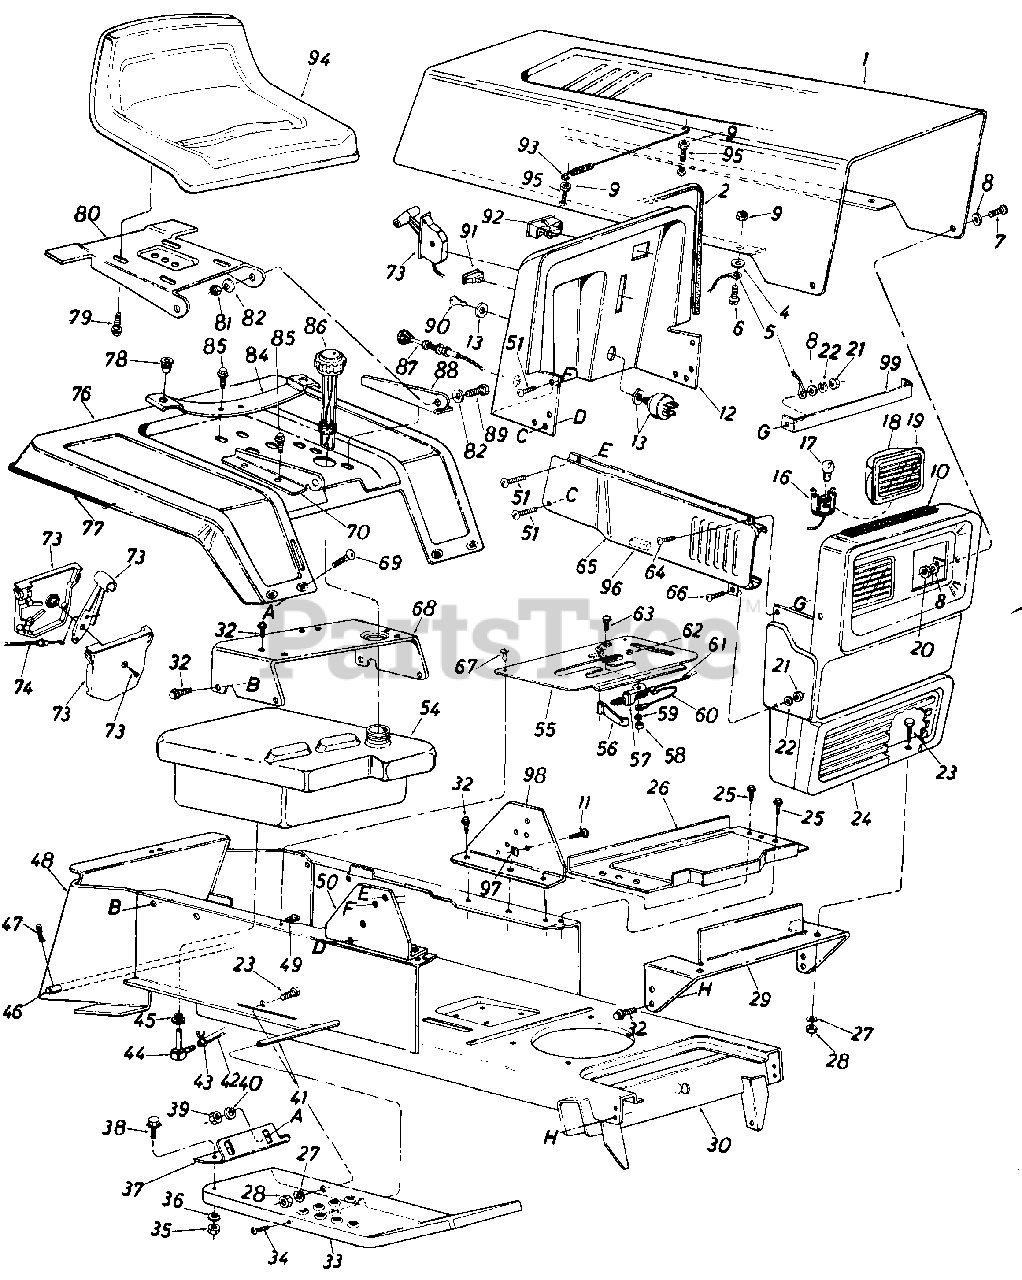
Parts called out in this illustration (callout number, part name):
1	Hood
2	Trim Strip-27" Lg.
4	Fl-Wash. .20" I.D. x .41" O.D.
5	Hood Stop
6	Truss Hd. Mach. Scr. #10-24 x.50" Lg.
7	Hex Bolt 1/4-20 x .62" Lg.
8	Fl-Wash. 1/4" I.D.
9	Hex Sem Nut #10-24 Thd.
10	Foam Strip 3/8" x 1" x 14"
11	Truss Mach. Scr. #10 x .50" Lg.
12	Dash Ass'y.
13	Ignition Switch
16	Socket
17	Lamp
18	Headlight Housing
19	Lens
20	Hex L-Nut 1/4-20 Thd.
21	Hex Nut 1/4-20 Thd.
22	L-Wash. 1/4" I.D.
23	Hex Bolt 5/16-18 x .75" Lg.
24	Grille (With Headlights)
25	Hex Wash. Hd. Scr. 1/4" x .50" Lg.
26	Battery Plate
27	L-Wash. 5/16" I.D.
28	Hex Nut 5/16-18 Thd.
29	Grille Mounting Bracket
30	Lower Frame Ass'y.
32	Hex Thd. Rolling Scr. 5/16-24 x .75" Lg.
33	Running Board-R.H.
34	Truss Mach. Scr. 5/16-18 x .75" Lg.
35	Hex Nut 5/16-18 Thd.
36	Bell-Wash. .34" I.D. x .87" O.D.
39	Hex Nut 1/4-20 Thd.
40	L-Wash. 1/4" I.D.*
41	Running Board Rod
42	Fuel Line 40" Lg.
43	Hose Clamp 3/8"
44	90ø Nipple
45	Bushing
46	Hitch Rod
47	Internal Cotterpin
48	Hitch Plate
49	Speed Nut
50	Dash Support Brkt.-R.H.
51	Hex Wash. Hd. Tap Scr. 1/4 x.75" Lg.
54	Fuel Tank
55	Transmission Cover Ass'y.
56	Switch Actuator Spring Lever
57	Safety Switch
58	Hex Nut 1/4-20 Thd.
59	L-Wash. 1/4" I.D.
60	Electric Wire
61	Reverse Lockout Wire Harness
62	Snap Bushing
63	Hex Bolt 1/4-20 x .50" Lg.*
64	Truss Hd. Scr. 1/4-20 x .75" Lg. *
66	Truss Mach. Scr. 1/4-20 x .50" Lg.*
67	Truss Mach. "B" Tap Scr. #10 x .50" Lg.
68	Seat Mounting Channel
69	Carriage Bolt 1/4-20 x .50" Lg.*
70	Seat Bracket-R.H.
73	Throttle Control Box Ass'y.
74	Throttle Control Cable
78	Grommet
79	Hex Wash. Hd. AB-Tap Scr. 3/8 x .75" Lg.
80	Seat Pivot Bracket
81	Hex Cent. L-Nut 5/16-18 Thd.
82	Belleville Wash. .34" I.D. x .88" O.D.
84	Seat Spring
85	Hex Wash. Hd. Self-Tap Scr. 5/16-18 x .50" Lg.
86	Gas Cap w/Gauge
87	Choke Control Comp.
88	Seat Bracket-L.H.
89	Hex Bolt 5/16-18 x .75" Lg.
90	Ignition Key
91	Light Switch
92	Ammeter
93	Hood Spring
94	Seat Ass'y.
95	Hex Screw #10-24 x 1.0" Lg.
96	Rubber Strip 1/2" Sq. x 2-1/2" Lg.
97	Speed Nut
98	Dash Support Brkt.-L.H.
99	Tie Strap-Grille/Side Panel
